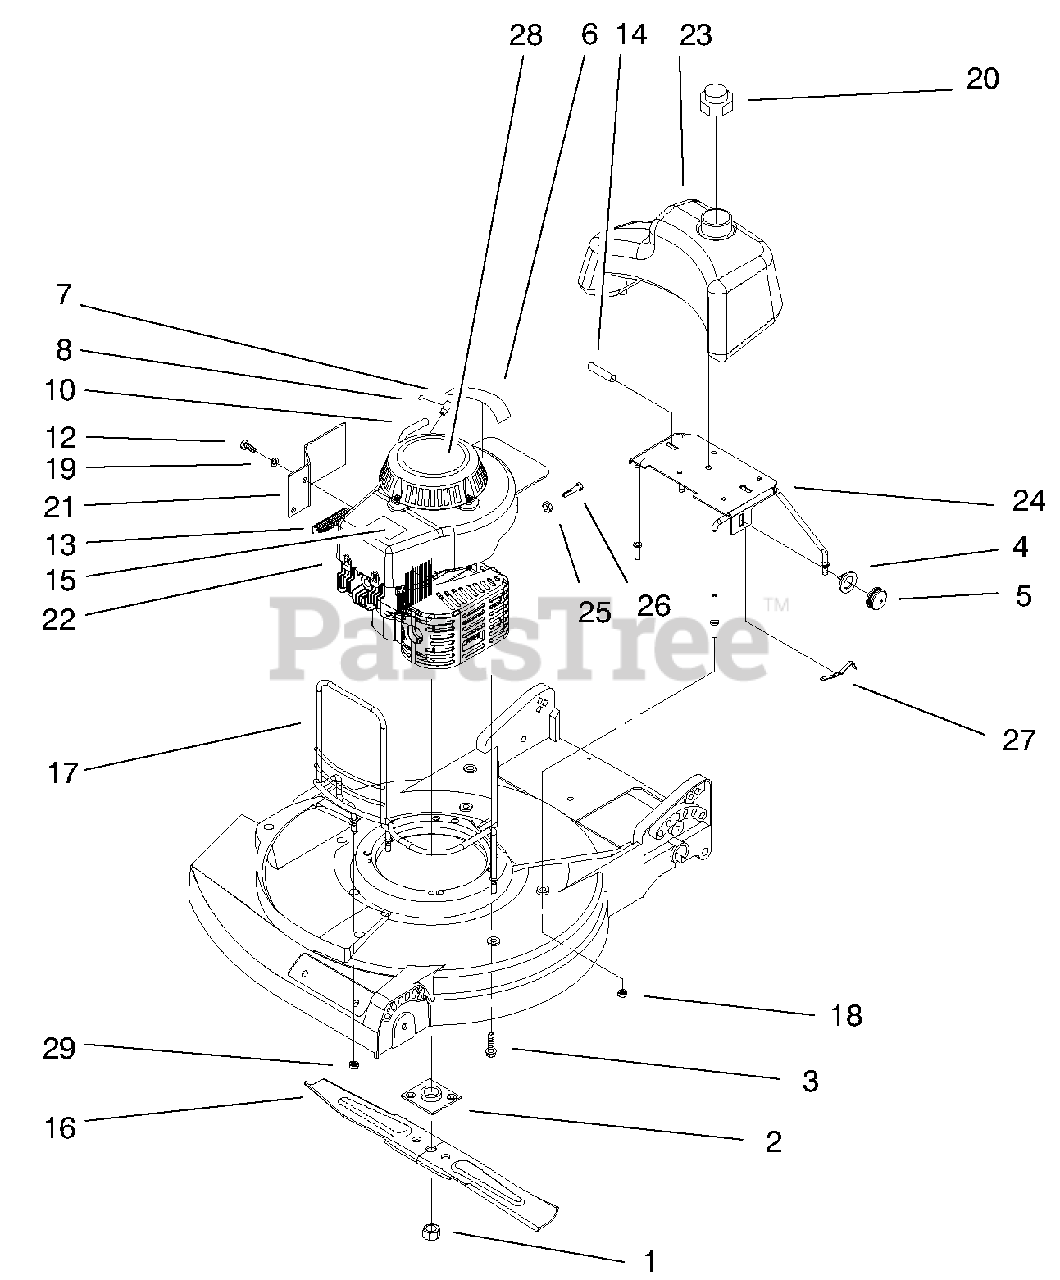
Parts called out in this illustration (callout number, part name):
1	Nut-Blade
2	ASM-Plate & Collar
3	Screw-Sems
4	Body-Primer
5	Bulb-Primer
6	Decal-Fuel Mix
7	Rope Stop
10	Gas Line
12	Screw-HH
13	Spring-Compression
14	Plug-Fuel Line
15	Decal-Lawn Boy
16	Blade-21" Whirl
17	Guard-Engine
18	Locknut
19	Washer-Lock
20	ASM-Fuel/Oil Cap
21	Guard-Brake
22	Engine Assembly
23	Tank-Fuel
24	Tank Bkt ASM
25	Nut-Throttle Cable
26	Screw-Throttle Cable
28	Decal-Recoil
29	Nut-Esna
